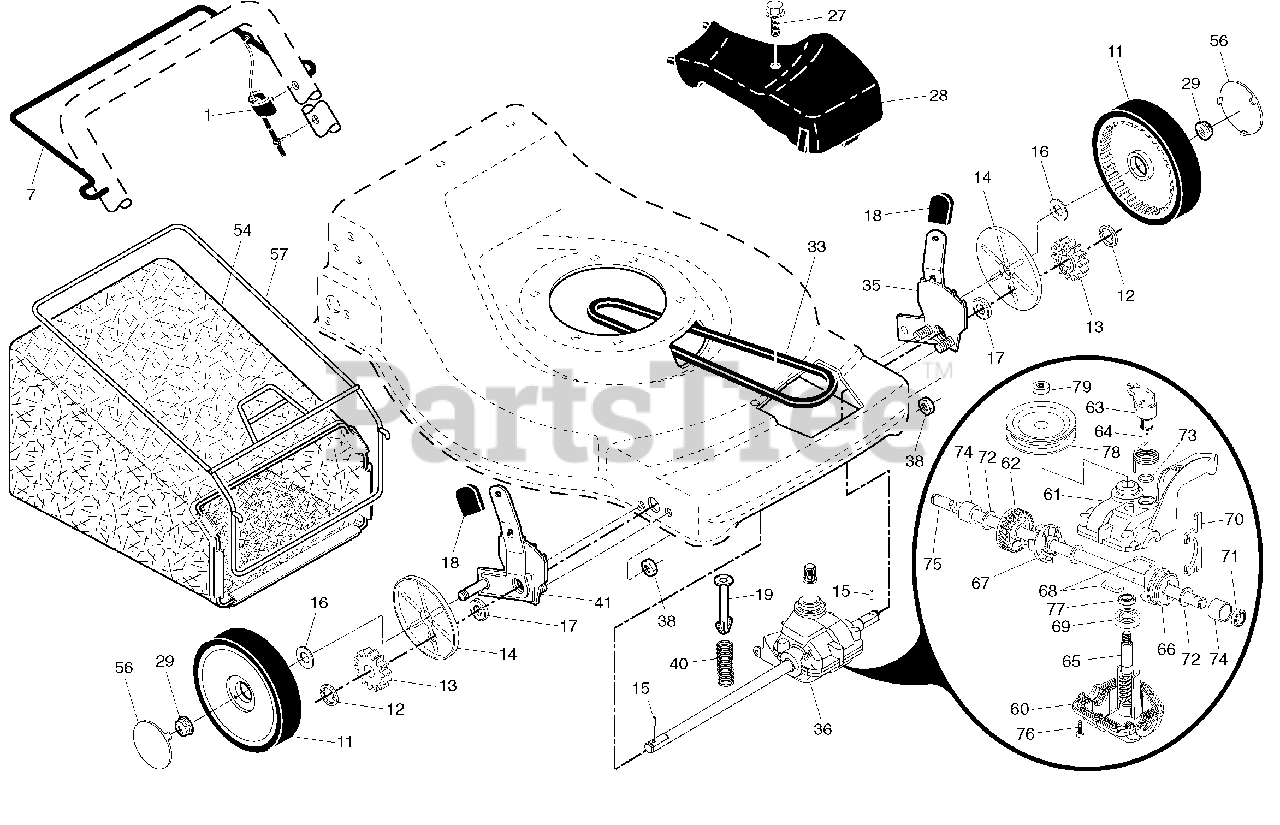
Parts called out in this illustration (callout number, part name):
1	Drive Control Assembly
6	Retainer, Spring
7	Bar, Drive Control
11	Wheel & Tire Assembly, Front
12	E-Ring
13	Pinion
14	Dust Cover
15	Pawl, Drive
16	Washer, Flat 3/8
17	Bearing, Wheel Adjuster
18	Selector Knob
27	Pan Head Tapping Screw #10-24 x 2-3/4
28	Drive Cover
29	Locknut, Hex
35	Kit, Wheel Adjuster, LH
36	Gear Case Assembly, Complete
38	Locknut 1/4-20
40	Spring
41	Kit, Wheel Adjuster, RH
54	Grassbag Assembly
56	Hubcap
57	Frame, Grassbag
60	Case, Lower
61	Case, Upper
62	Gear, 27 Teeth
63	Lever, Clutch
64	Spring, Return
65	Shaft, Input
66	Dog, Movable
67	Dog, Fixed
68	Wire, Formed
69	Bearing, Ball
70	Fork, Shift
71	Seal, Output Shaft
72	Washer
73	Seal, Case
74	Bushing
75	Shaft, Output
76	Screw
77	Seal, Input Shaft
78	Pulley, Drive
79	Locknut, Hex
